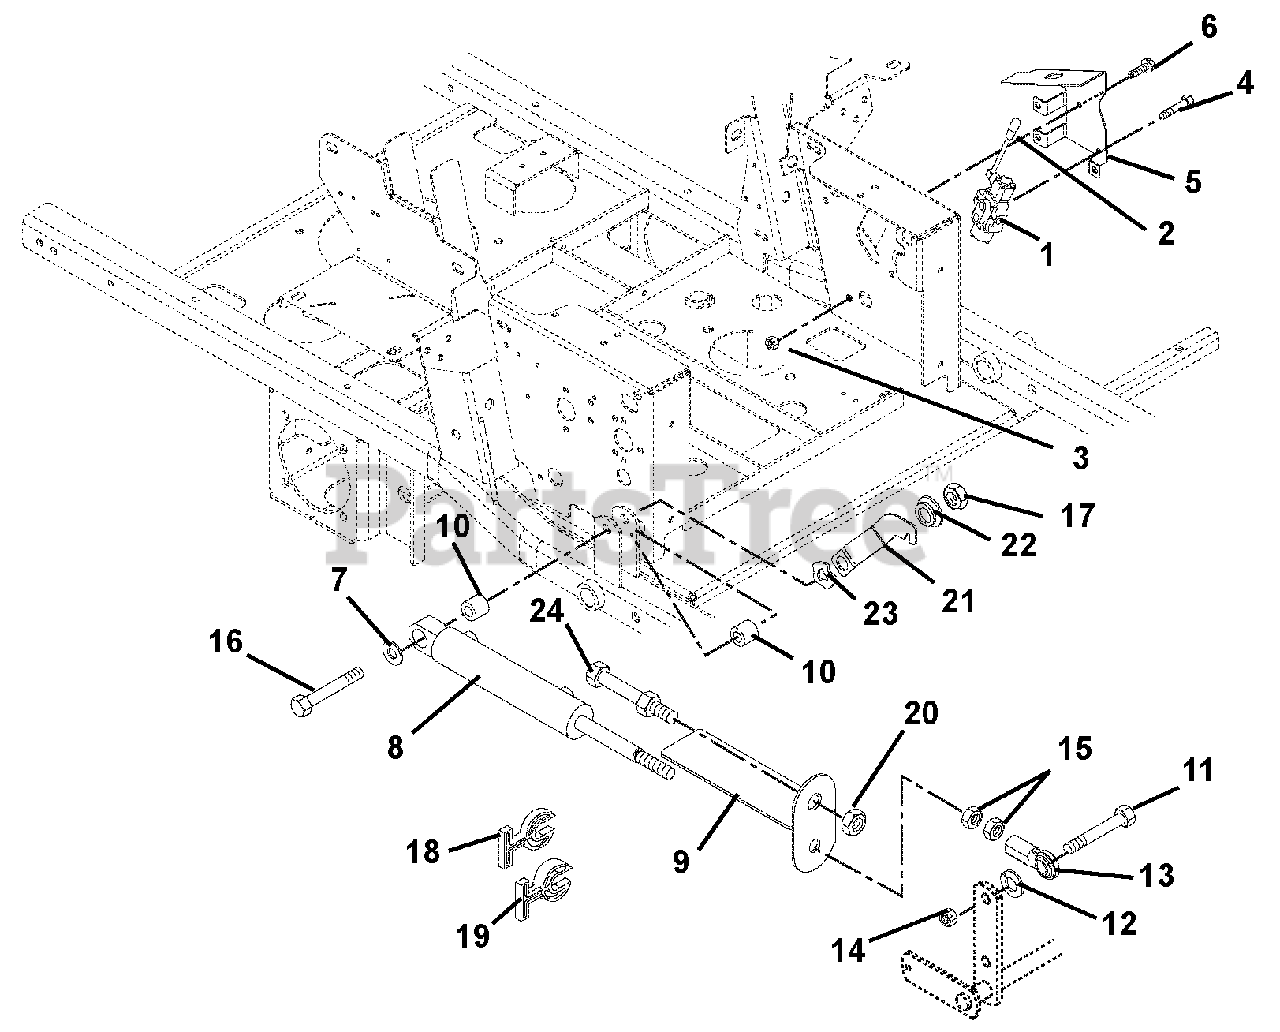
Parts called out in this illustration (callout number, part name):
1	Valve, Hydraulic
2	Knob (Service Only)
3	Nut, Locking Top Flange .31-18
4	Bolt, Hex .31-18 x 2.5 Grade 5
5	Bracket, Valve Mounting
6	Screw, Tapping .38-16 x .50 Hex Washer Head
7	Washer, Flat Steel .515 x 1.625 x .25
8	Cylinder, Hydraulic Lift
9	Strap, Cut Indicator / Guard
10	Bushing .516 x 1.00 x 1.05
11	Bolt, Hex .62-11 x 2.25 Grade 8
12	Washer, Lock .62 x .156
13	Rod End, Right Hand Female .625
14	Nut, Locking Center .62-11
15	Nut, Jam .625-18
16	Bolt, Hex .50-13 x 3.75 Grade 5
17	Nut, Locking Top Flange .50-13
18	Stop, Cylinder .34 Thick
19	Stop, Cylinder .68 Thick
20	Nut, Jam .75-16
21	Latch, Footboard
22	Bushing, Flange .515 x .75 x .275 x 1.12
23	Washer, Wave .076 x 1.12 x .08
